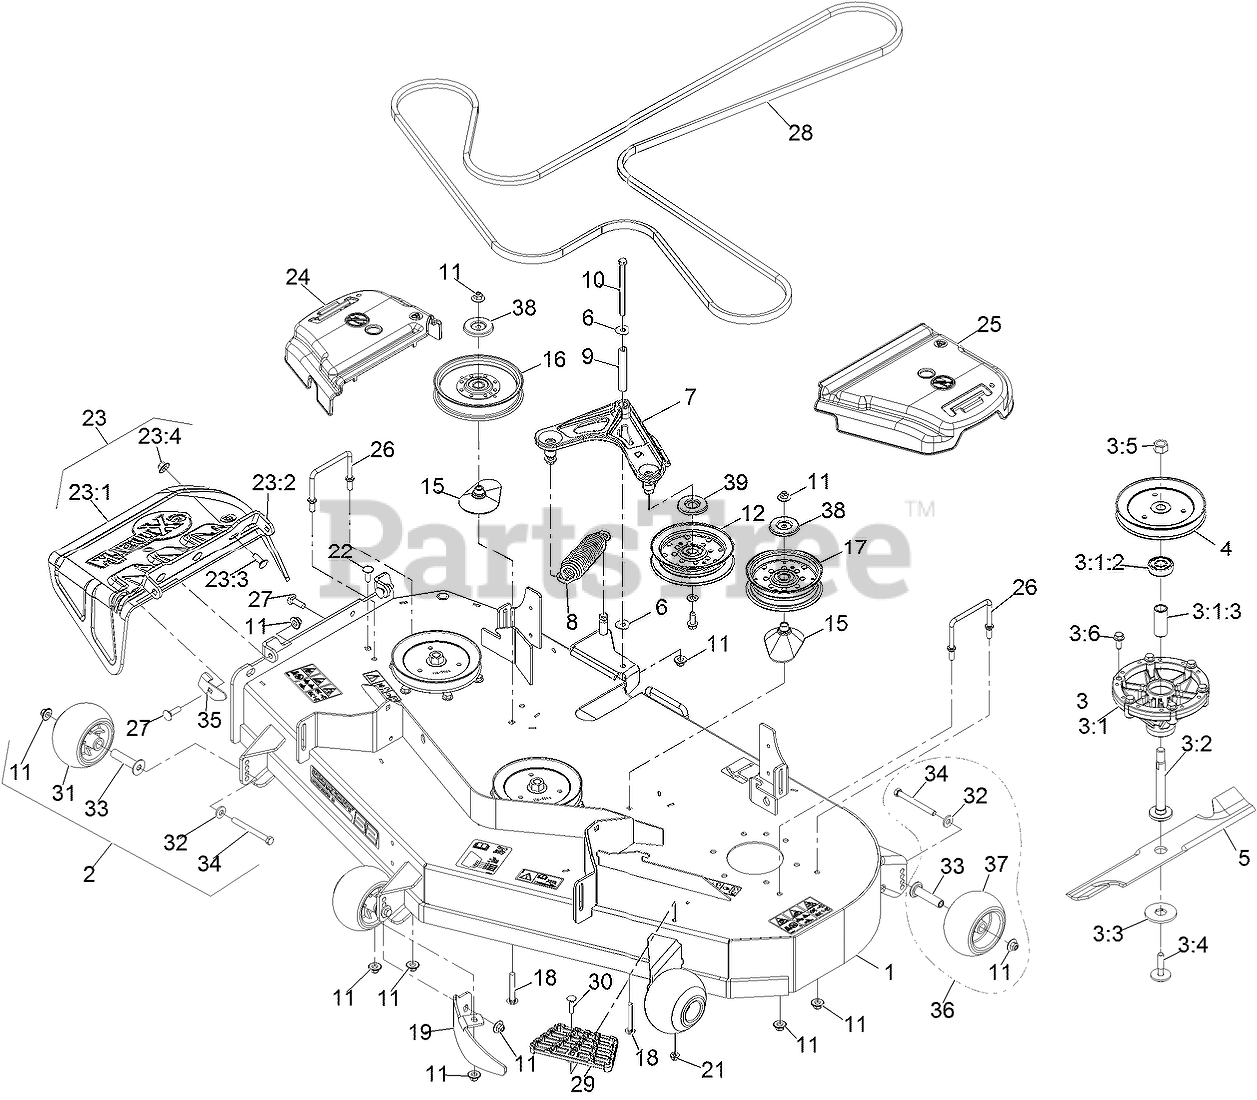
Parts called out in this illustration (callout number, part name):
1	ASM-DECK W/DECALS 523
2	KIT, ANTI-SCALP ROLLER
3	ASM, CUTTER HOUSING COMPLETE
3:1	ASM-CUTTER HOUSING
3:1:2	BEARING
3:1:3	SPACER-BEARING
3:2	SPINDLE-HEX PILOT
3:3	WASHER-HEX BLADE DRIVE
3:4	BOLT-BLADE, SEM
3:5	NUT-HEX
3:6	SCREW-FORMING, THREAD
4	SHEAVE,BLADE DRIVE 6.50
7	IDLER ARM ASM
8	SPRING-EXTENSION
9	BUSHING
10	SCREW-HH
11	Nut-Nyloc 3/8-16 Flg
12	IDLER-PULLEY, FLAT
15	SPACER-PULLEY
16	IDLER-PULLEY, FLAT 6.00X1.00
17	IDLER-PULLEY, FLAT 5.00X1
18	SCREW-CARR
19	BAFFLE-DOGLEG, LZE-PNS-52
21	NUT-HF, NI
22	SCREW-CARR
23	ASM,DISCHARGE CHUTE
23:1	CHUTE,DISCHARGE
23:2	BRACKET,DISCHARGE CHUTE
23:3	SCREW-CARR
23:4	Nut-Nyloc 3/8-16 Flg
24	COVER-BELT, RH
25	COVER-BELT, LH
26	WIREFORM-COVER
27	BOLT-CARR
29	STEP-DECK
30	Bolt-Carriage 5/16-18 X 1 1/4
31	ROLLER-SCALP, ANTI
32	WASHER-BELLEVILLE
33	AXLE, ROLLER
34	SCREW-HH 3/8-16 X 3 3/4 GR 8
35	STOP-DISCHARGE CHUTE
36	KIT-ANTISCALP ROLLER
37	ROLLER-SCALP, ANTI
38	SHIELD-DUST
39	SHIELD-GUARD, DUST
